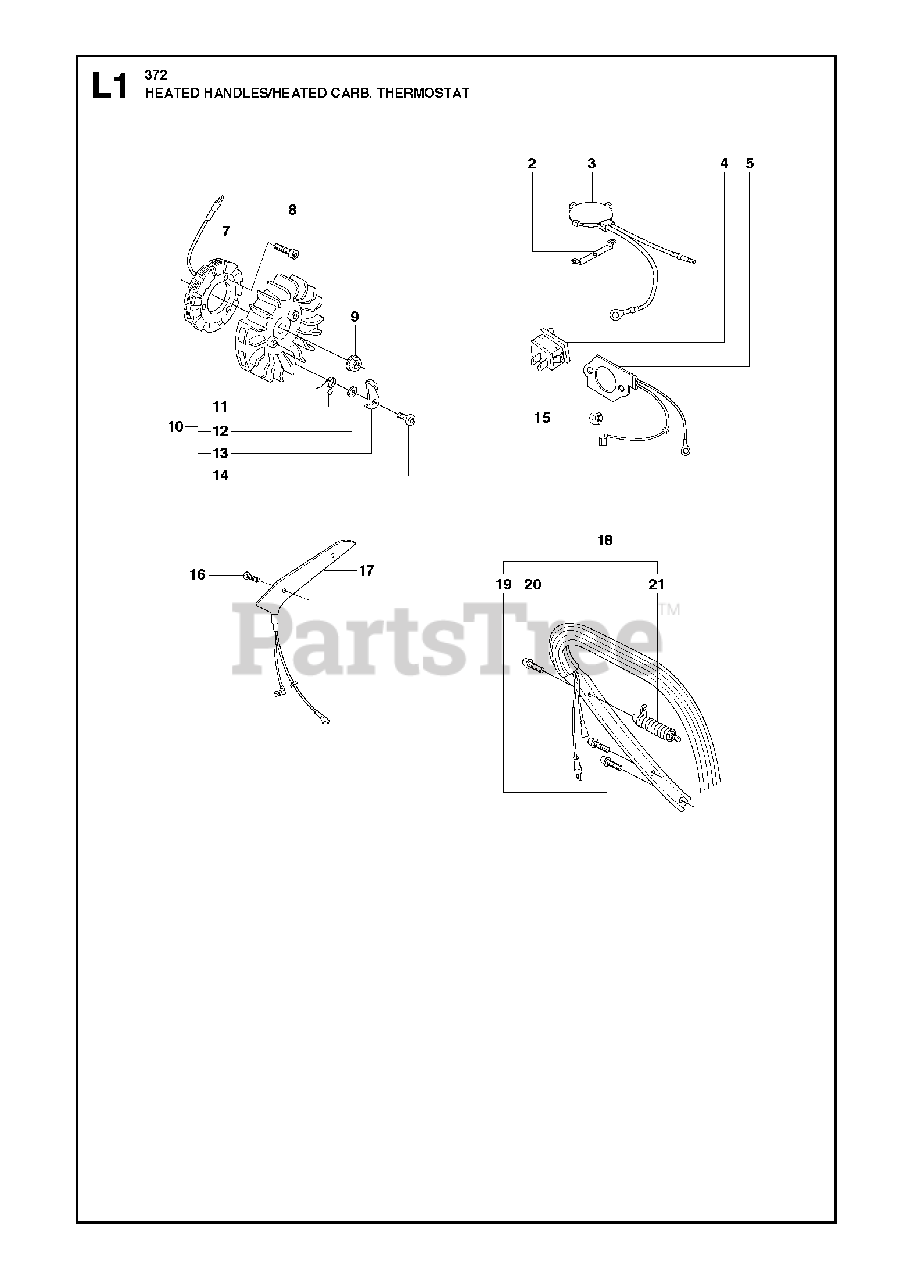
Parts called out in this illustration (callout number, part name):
3	THERMOSTAT
5	FOIL ELEMENT
9	NUT W/ WASHER
11	SPRING
12	WASHER
13	PAWL
14	SCREW M5X14
18	FRONT HANDLE (G)
19	SCREW
20	SCREW
21	ANTIVIBE MOUNT
